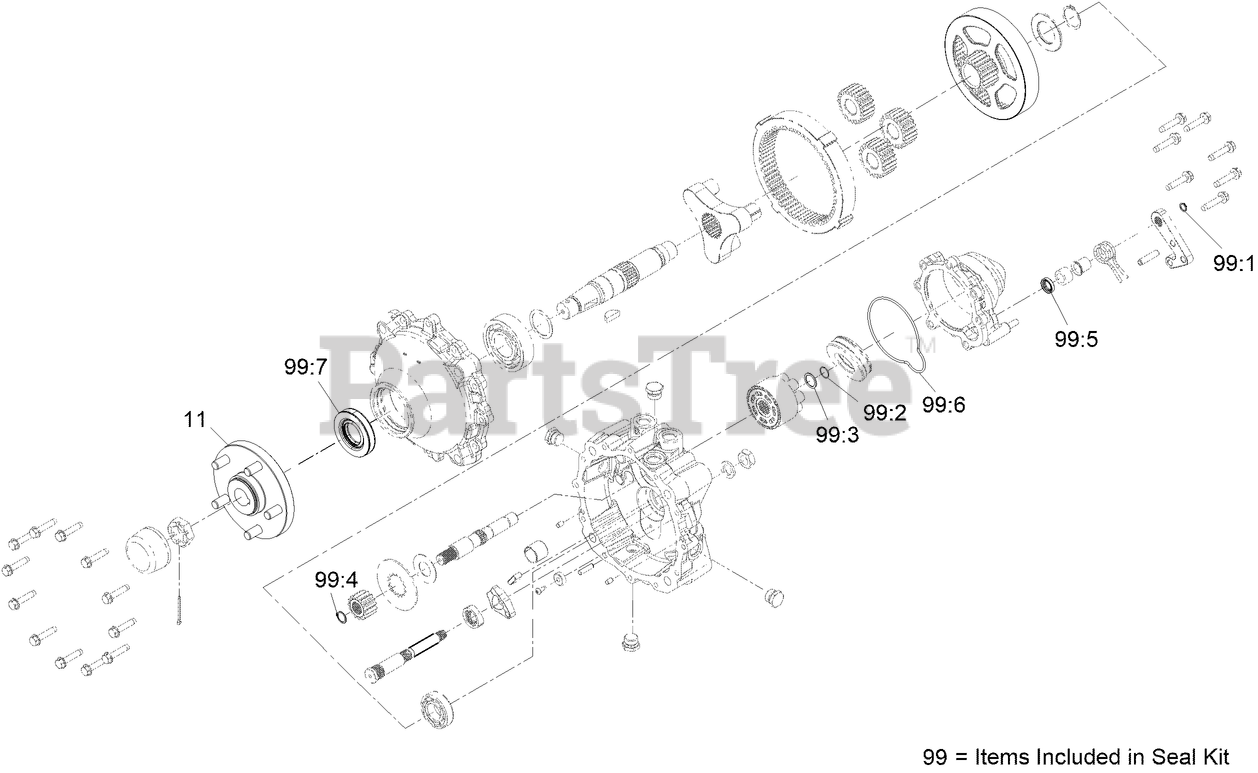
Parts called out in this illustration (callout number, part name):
11	5 STUD WHEEL HUB KIT
99	SEAL KIT
99:1	RETAINER RING
99:2	RING-RETAINING
99:4	RING-RETAINING
99:5	Seal, Brake
99:6	O-Ring, Round
99:7	Seal, Axle
